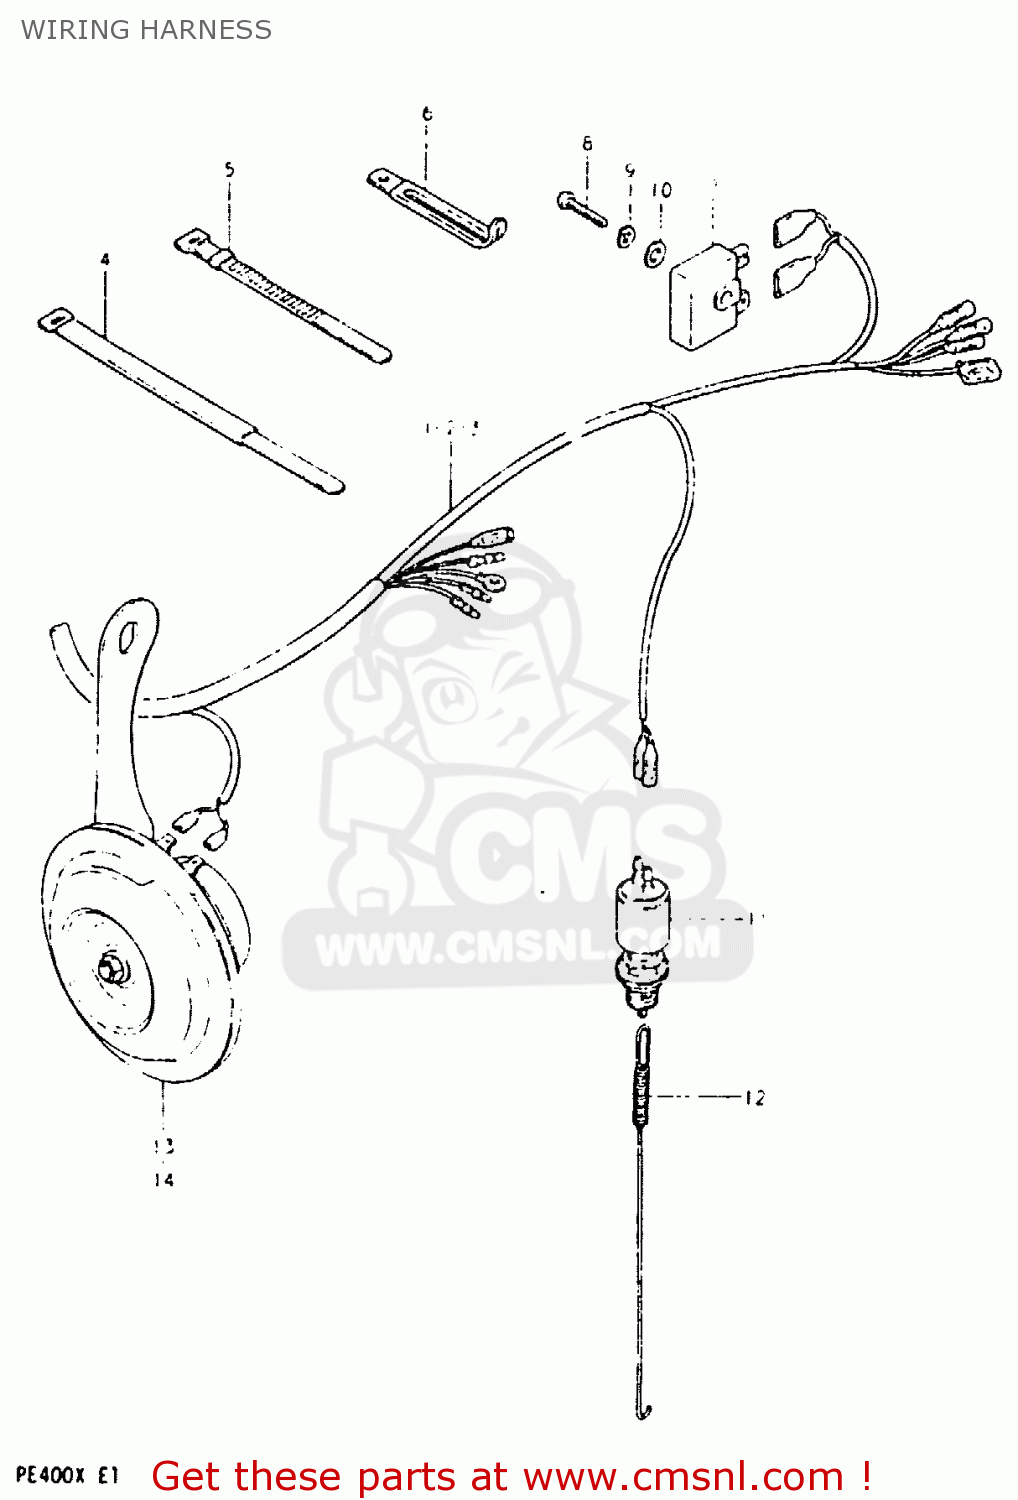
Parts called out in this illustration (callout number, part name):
2	WIRING HARNESS
4	CLAMP
5	CLAMP(L:120)
6	CLAMP
11	SWITCH ASSY,BRAKE LAMP
12	SPRING
13	HORN (WHITE)
